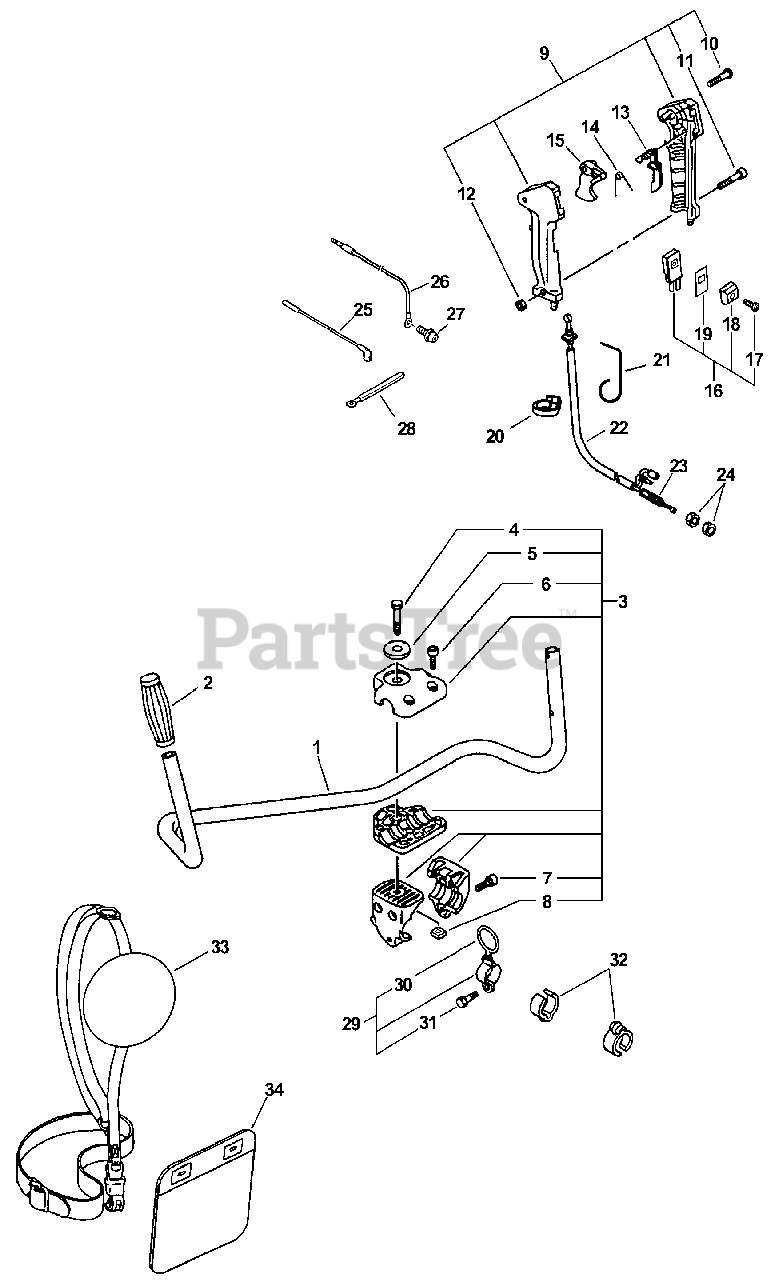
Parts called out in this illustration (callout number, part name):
1	HANDLE - FRONT
2	GRIP, HANDLE - LEFT
3	HANDLE BRACKET KIT
4	BOLT - 8X55
5	WASHER - 8
6	SCREW - 5X20
7	SCREW - 5X30
9	THROTTLE CONTROL ASSY
10	SCREW - 3X25
11	SCREW - 5X30
13	LOCKOUT, THROTTLE
14	SPRING, LOCKOUT LEVER
15	TRIGGER, THROTTLE
16	IGNITION SWITCH ASSY
17	SCREW - 3X10
18	KNOB, SWITCH - ORANGE
19	COVER, SWITCH - STOP
22	TUBE, PROTECTIVE - CORRUGATED
23	CABLE, THROTTLE
25	LEAD - IGNITION
26	LEAD - GROUND
27	SCREW - 5X10
29	HANGER KIT
31	BOLT - 5X12
33	HARNESS ASSY
34	CUSHION
